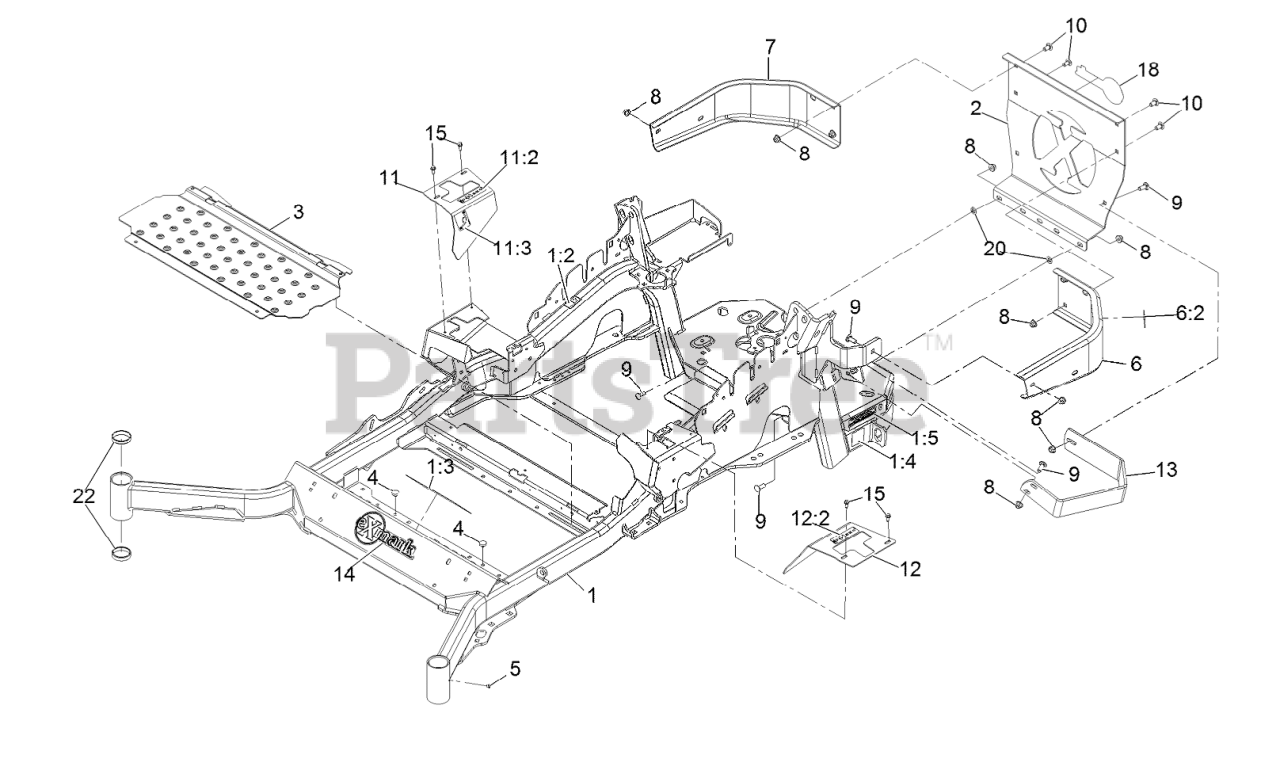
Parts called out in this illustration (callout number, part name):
1	MAINFRAME ASM
1:2	DECAL-WARNING
1:3	DECAL-DANGER
1:4	DECAL-HAZARD, PINCHED FINGER
1:5	DECAL-SPARK ARRESTER
2	PLATE,REAR GUARD
6	LH BUMPER ASM
6:2	DECAL-WARNING
7	BUMPER-RH
8	NUT-HF, NI
9	SCREW-CARR
10	SCREW-CARR
11	RH MOTION CONTROL COVER ASM
11:2	DECAL-CONTROL, MOTION
11:3	DECAL-PARK BRAKE, CE
12	LH MOTION CONTROL COVER ASM
12:2	DECAL-CONTROL, MOTION
13	GUARD-MUFFLER
14	DECAL-EXMARK LOGO
15	SCREW-HWH
18	DECAL-EXMARK LOGO
19	Decal-Patent Ttco.Com
20	NUT-PUSH
21	DECAL-FUEL FILL, CE
22	CUP-BEARING
